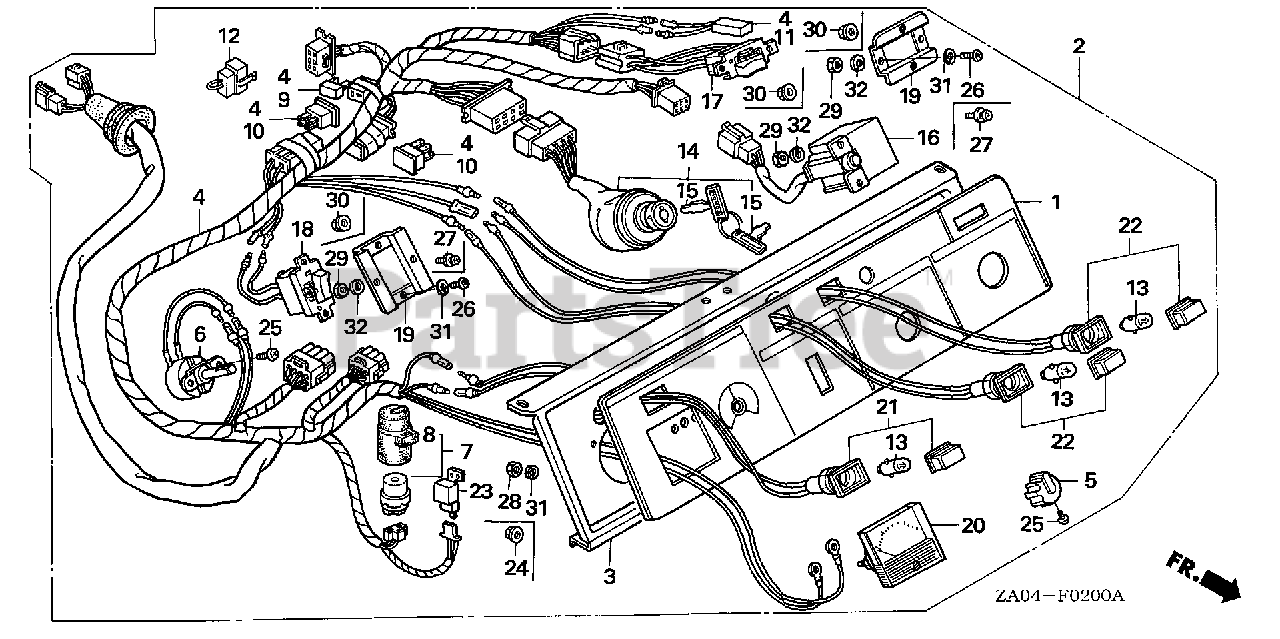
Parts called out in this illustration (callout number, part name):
1	MARK, CONTROL PANEL
2	PANEL ASSY., CONTROL *NH105* (MAT BLACK)
2	PANEL ASSY., CONTROL *NH105* (MAT BLACK) (NOT AVAILABLE)
3	PANEL, CONTROL *NH105* (MAT BLACK)
4	HARNESS ASSY., CONTROL (NOT AVAILABLE)
4	HARNESS ASSY., CONTROL
5	KNOB, ADJUSTING
6	RESISTOR, VARIABLE
7	RELAY ASSY.
8	SUSPENSION
10	STACK ASSY., DIODE (2.7A)
12	CONNECTOR ASSY.
13	BULB, WEDGE BASE (12V/2W)
13	BULB, DASH (24V-2W)
14	SWITCH ASSY., COMBINATION
15	KEY
16	RELAY, ALERT
17	SWITCH ASSY., CONTROL
18	SWITCH ASSY., IDLE CONTROL
19	STAY, SWITCH (NOT AVAILABLE)
20	METER ASSY., VOLT (300V)
21	SOCKET ASSY., LAMP (GREEN)
22	SOCKET ASSY., LAMP (RED)
25	SCREW, PAN (3X6)
26	SCREW, PAN (3X8)
28	NUT, HEX. (3MM)
29	NUT, HEX. (4MM)
31	WASHER, SPRING (3MM)
32	WASHER, SPRING (4MM)
